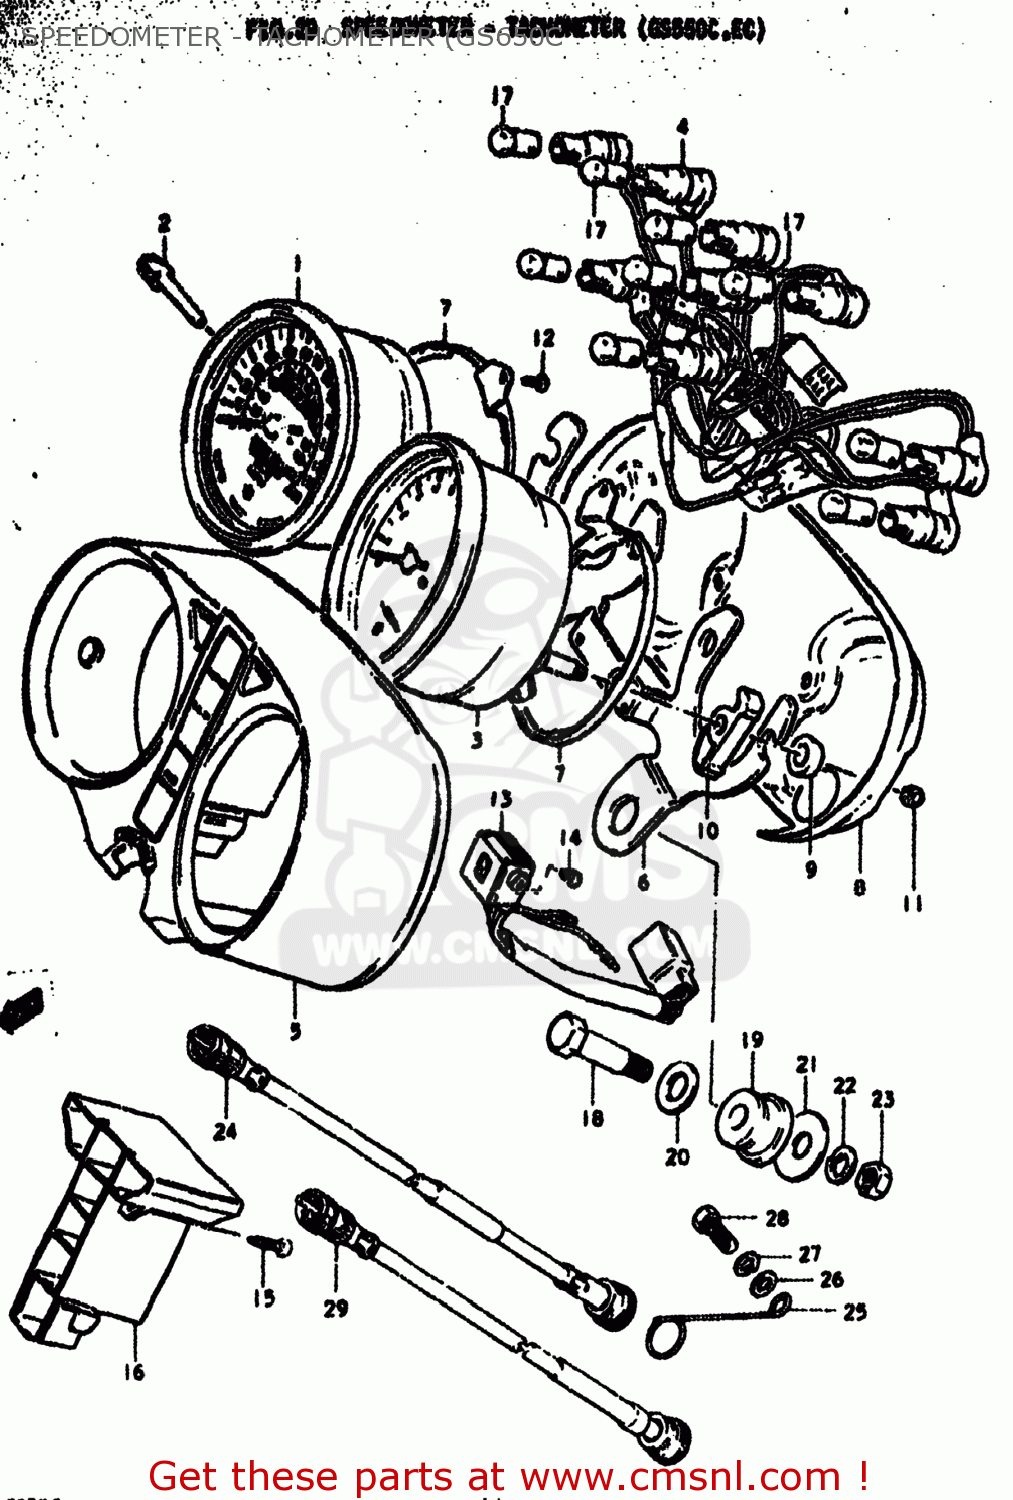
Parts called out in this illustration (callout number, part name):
1	SPEEDOMETER ASSEMBLY
2	KNOB
3	TACHOMETER
4	SOCKET,METER
5	CASE SET,METER
6	BRACKET,COMBINATION METER
7	PLATE,METER,UNDER
8	PLATE,UNDER
9	CUSHION,METER (A)
10	CUSHION,METER (B)
11	NUT
12	SCREW
13	INDICATOR ASSEMBLY,GEAR POSITION
15	SCREW
16	CASE,PILOT BOX,INNER
17	BULB(12V3.4W,STANLEY,A72A)
18	BOLT(8X31)
19	CUSHION,METER
20	WASHER
21	WASHER (8.5X29X1.6)
22	LOCK WASHER
23	NUT
24	CABLE ASSEMBLY,SPEEDOMETER
25	GUIDE,SPEEDOMETER CABLE
26	WASHER 6MM
27	LOCK WASHER
28	BOLT, UPPER
29	CABLE ASSEMBLY,TACHOMETER
